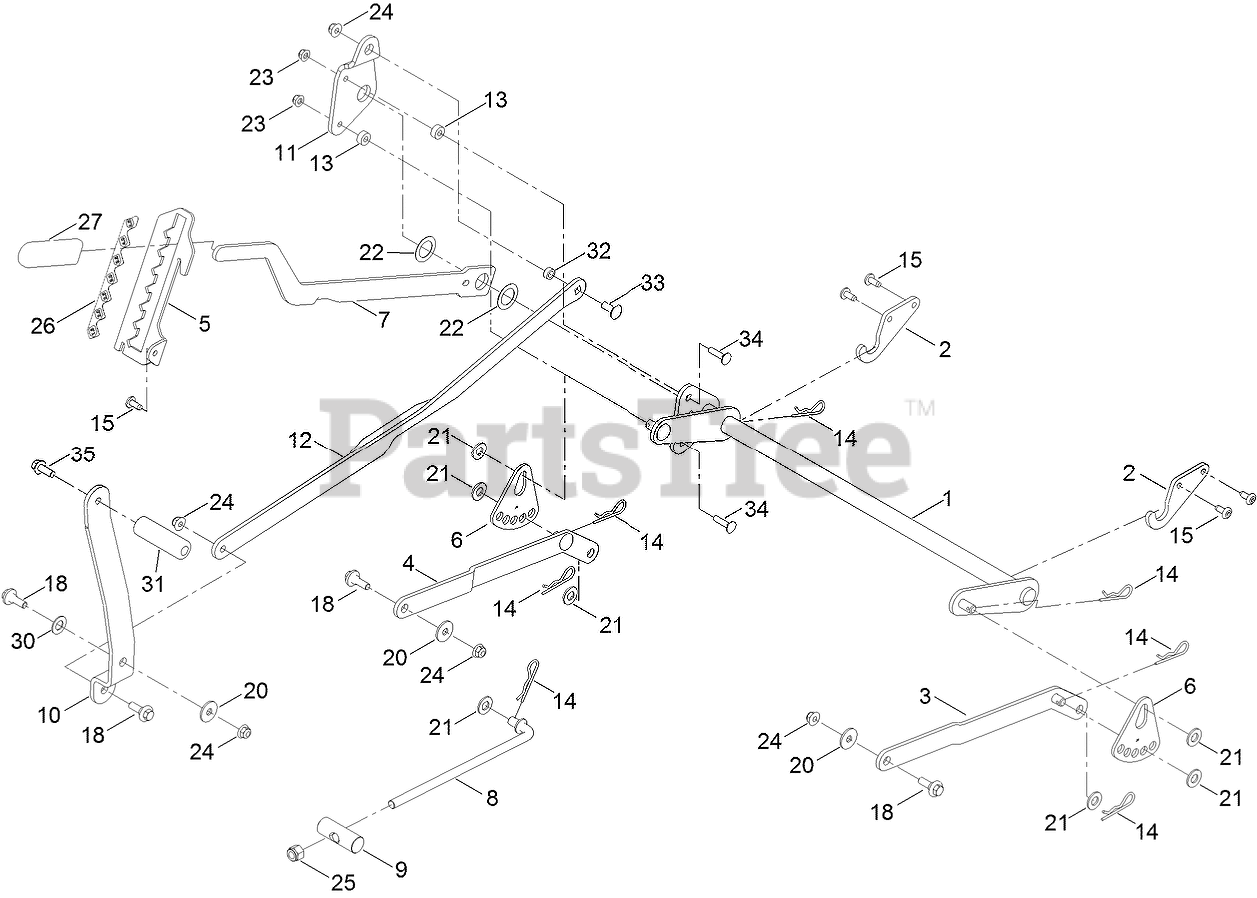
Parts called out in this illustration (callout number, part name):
1	DECK LIFT ASM
2	BRACKET-PIVOT, DECKLIFT
3	LH ARM ASM
4	RH ARM ASM
5	BRACKET-HOC
6	PLATE-HOC ADJUSTMENT
7	LEVER-LIFT
8	ROD-MOUNT, DECK
9	PIN-PIVOT
10	PEDAL-LIFT
11	PLATE-FOOTLIFT
12	LINK ASM
13	SPACER
14	PIN-COTTER
18	SCREW-SHOULDER
20	WASHER-HARDENED
21	WASHER-FLAT
22	WASHER-THRUST
23	NUT-HF, NI
24	NUT-HF, NI
25	NUT-HEX
26	DECAL-HOC
27	GRIP-LEVER
30	WASHER-NYLON
31	PEDAL-FOOT LIFT
32	SPACER
34	SCREW-CARR
35	SCREW-HHF
